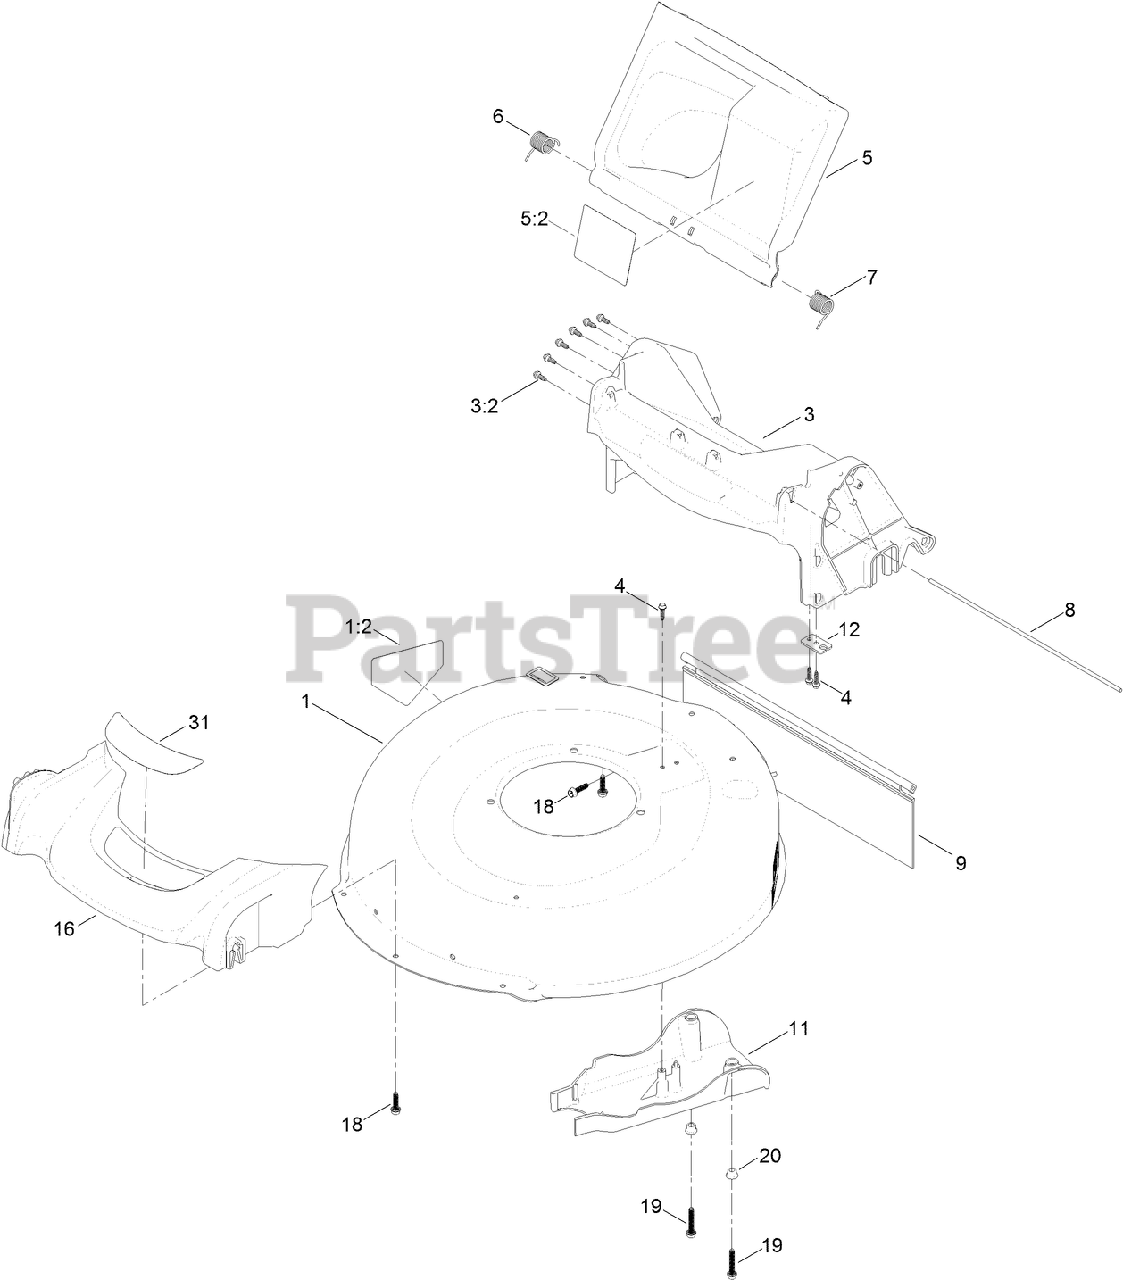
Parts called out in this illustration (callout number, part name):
1:2	DECAL-DANGER
4	SCREW-HWH
5	REAR DEFLECTOR ASM
5:2	DECAL-WARNING
6	SPRING-TORSION
7	SPRING-TORSION
9	SHIELD-TRAILING
11	COVER-BELT
12	BRACKET-CABLE
18	SCREW-FLANGE, PLASTIC
19	SCREW-FLANGE, SERRATED
20	SPACER-FLANGE
31	DECAL-DECK
